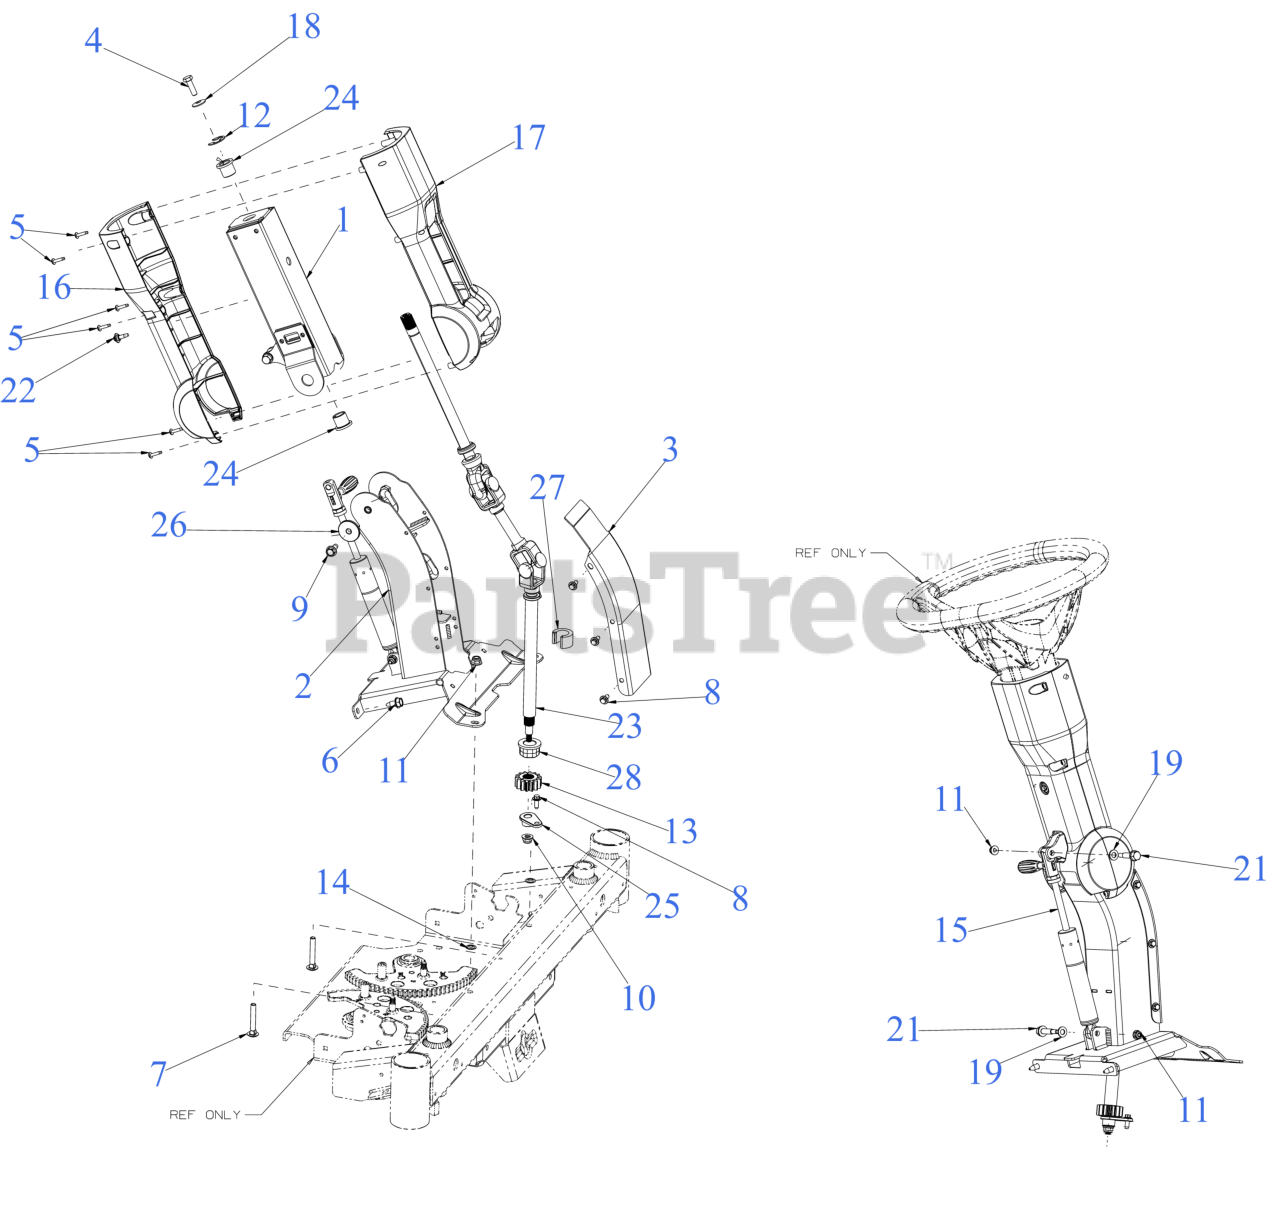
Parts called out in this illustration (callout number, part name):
1	STEERING COLUMN (UPPER)
2	STEERING COLUMN (LOWER)
2	LOWER STEERING COLUMN
3	STEERING COLUMN COVER
4	HEX HEAD CAP SCREW 5/16-24 x 1.00 GR5
5	SCREW 8-16 x 3/4
6	SCREW 5/16-18 x .750
7	CARRIAGE BOLT 5/16-18 x 2.00 GR5
8	SCREW M6-1 x .625
9	SCREW 5/16-18 x .750
10	FLANGE LOCK NUT 5/16-18
11	FLANGE LOCK NUT
13	STEERING GEAR 14T
15	TILT STEERING CYLINDER
16	STEERING COLUMN COVER (BACK)
17	STEERING COLUMN COVER (FRONT)
18	BELL WASHER .337 X.867 x .057
19	FLAT WASHER
21	SHOULDER SCREW
22	SHOULDER SCREW M6-1 .368 X.115
23	STEERING SHAFT
24	FLANGE BEARING .631 ID
25	FLANGE BEARING
26	SHOULDER SPACER
27	SPACER: .76ID x .75
27	SNAP SPACER
28	HEX FLANGE BEARING
